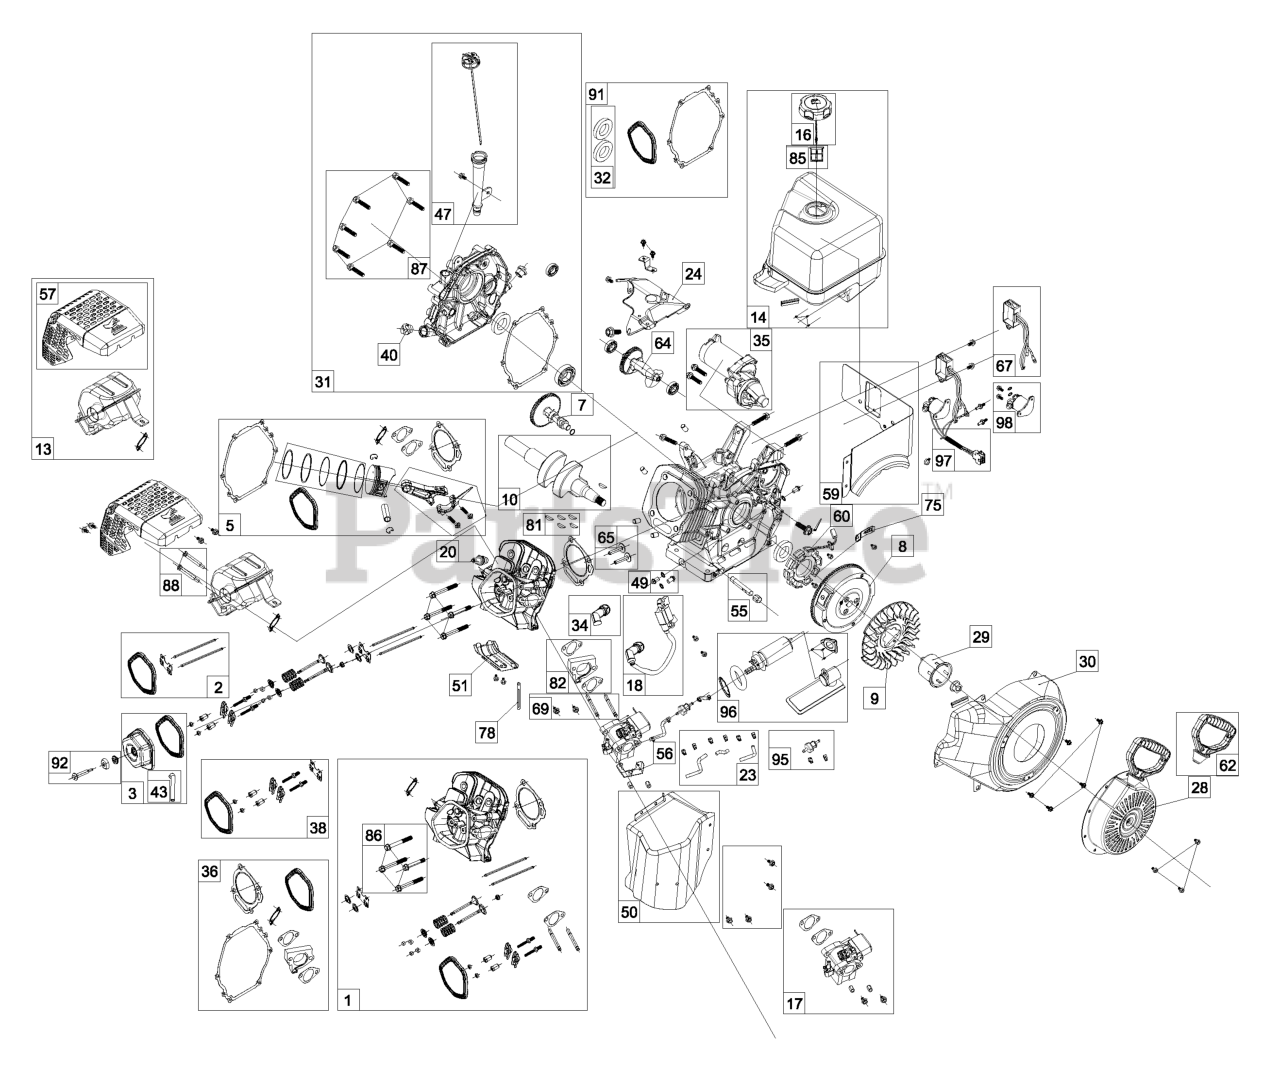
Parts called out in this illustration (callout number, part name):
1	CYLINDER HEAD 420CC
2	PUSH ROD & PLATE KIT (W/GSKT)
3	VALVE COVER (W/GASKET)
5	PISTON AND ROD ASSEMBLY
7	CAMSHAFT - MCR
8	FLYWHEEL - ELECTRIC START
9	COOLING FAN - FLYWHEEL
10	CRANKSHAFT
13	MUFFLER ASSEMBLY - GEN III
14	FUEL TANK ASSEMBLY
16	CAP, FUEL TANK (RED)
17	THROTTLE BODY ASSM, EFI- 369CC
18	IGNITION COIL (CDI) (STANDARD)
20	SPARK PLUG, ARIENS AX
23	FUEL HOSE KIT, QTY 3 W/CLAMPS
24	SPEED CONTROL SHIELD (GEN III)
28	RECOIL STARTER, ROUND STYLE
29	STARTER CUP, ROUND STYLE
30	BLOWER HOUSING, MATT BLK-EFI
31	CYL COVER, COMP ASSEMBLY-EFI
32	OIL SEAL KIT
34	SPARK PLUG BOOT (W/MTL SHIELD)
35	ELECTRIC STARTER, 12 VOLT
36	ENGINE GASKET KIT
38	ROCKER ARM KIT (W/GASKET)
40	NON-REMOVABLE PLASTIC PLUG
43	BREATHER TUBE
47	HIGH OIL-FILL TUBE & CAP
49	OIL DRAIN PLUG (W/WASHER)
50	HEATER BOX (MATTE BLACK)-EFI
51	SHIELD - CYLINDER
55	OIL DRAIN TUBE W/CAP NUT
56	CARBURETOR VAPOR SHIELD
57	MUFFLER HEAT SHIELD - GEN III
59	FUEL TANK SKIRT EFI
60	CHARGING COIL (250 WATT)
62	STARTER GRIP
64	COUNTER WEIGHT KIT
65	TAPPET KIT (SET OF 2)
67	REGULATOR / RECTIFIER (250 W)
69	CARB MTG STUD KIT 414CC
72	LABEL KIT (EFI)
75	SHIELD - FLYWHEEL
77	RECOIL BOLT KIT
78	BREATHER TUBE RETAINING STRAP
81	WOODRUFF FLYWHEEL KEY 5-PACK
82	CARBURETOR SPACER
85	FUEL TANK STRAINER
86	HEAD BOLT KIT 291-414CC
87	CRANKCASE COVER BOLT KIT 414CC
88	MUFFLER SHOULDER BOLT
91	CRANKCASE GASKET KIT(369-414)
92	VALVE COVER BOLT (SINGLE BOLT)
95	FUEL FILTER, IN-LINE
96	FUEL PUMP-EFI W/P-FLTER&SCRWS
97	HARNESS, 6 PIN WIRE
98	SOLENOID, STARTER (W/SCREWS)
9999	HARDWARE KIT (4 M6X10 FLG BLT)
9999	OIL, ARIENS 5W30 32 OUNCE, SYNTHETIC BLEND
